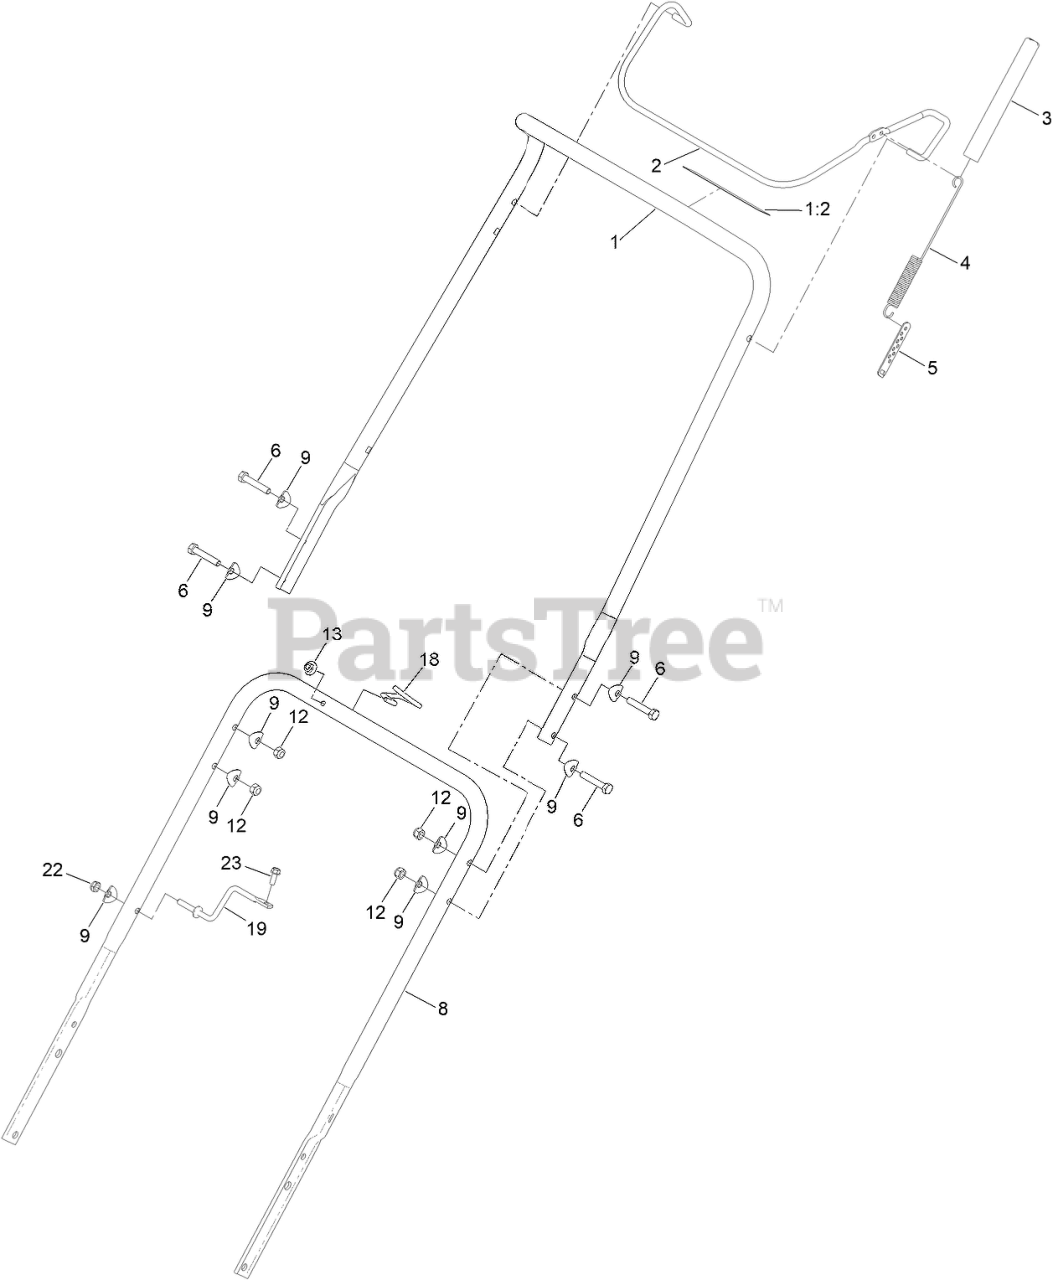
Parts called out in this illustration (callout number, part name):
1	UPPER HANDLE ASM (W/ DECAL)
1:2	DECAL-DRIVE, ROTOR
2	BAIL-CONTROL
3	COVER-SPRING
4	SPRING-EXTENSION, CLUTCH
5	ADJUSTER-CLUTCH CABLE
6	SCREW-HH
8	HANDLE-LOWER
9	WASHER
12	NUT-LOCK, NI
13	NUT-HF
18	GUIDE-ROPE
19	SUPPORT-BOX, SWITCH
22	NUT-LOCK, NI
23	SCREW-HWH
